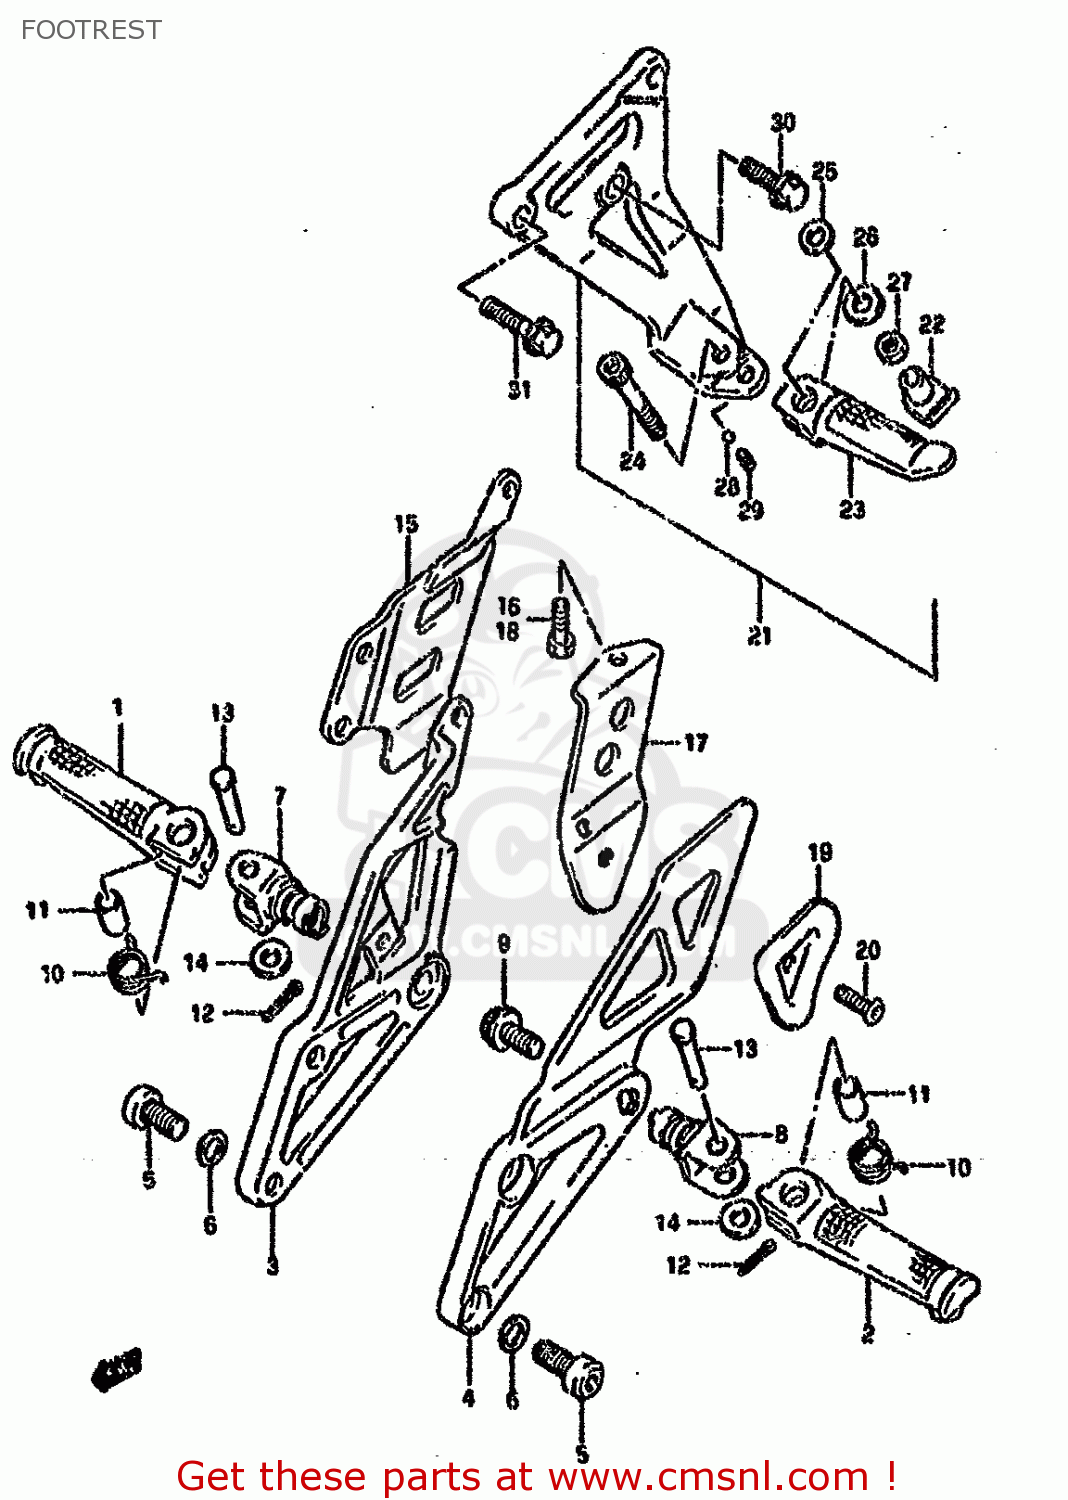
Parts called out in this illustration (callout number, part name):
1	BAR,FOOTREST,R
2	BAR,FOOTREST,L
3	BAR,FRONT FOOTREST
4	BRACKET,FRONT FOOTREST
5	BOLT
6	WASHER
7	HOLDER,FOOTREST,RIGHT
8	HOLDER,FOOTREST,L
9	BOLT(10X24)
10	SPRING
11	SPACER(8.1X12X22)
12	PIN 20X15
13	PIN
14	WASHER(8.5X18X1)
15	GUARD,FRONT FOOTREST,RIGHT
16	BOLT
17	HOLDER,FOOTREST,RIGHT
18	BOLT
19	PLATE,REINFORCEMENT,L
20	SCREW(6X12)
21	FOOTREST ASSEMBLY,PILLION
22	BOSS,PILLION FOOTREST,R
23	BAR,PILLION FOOTREST R
24	BOLT
25	WASHER(8.5X18X1)
26	WASHER
27	NUT
28	BALL
29	SPRING
30	BOLT
31	BOLT
